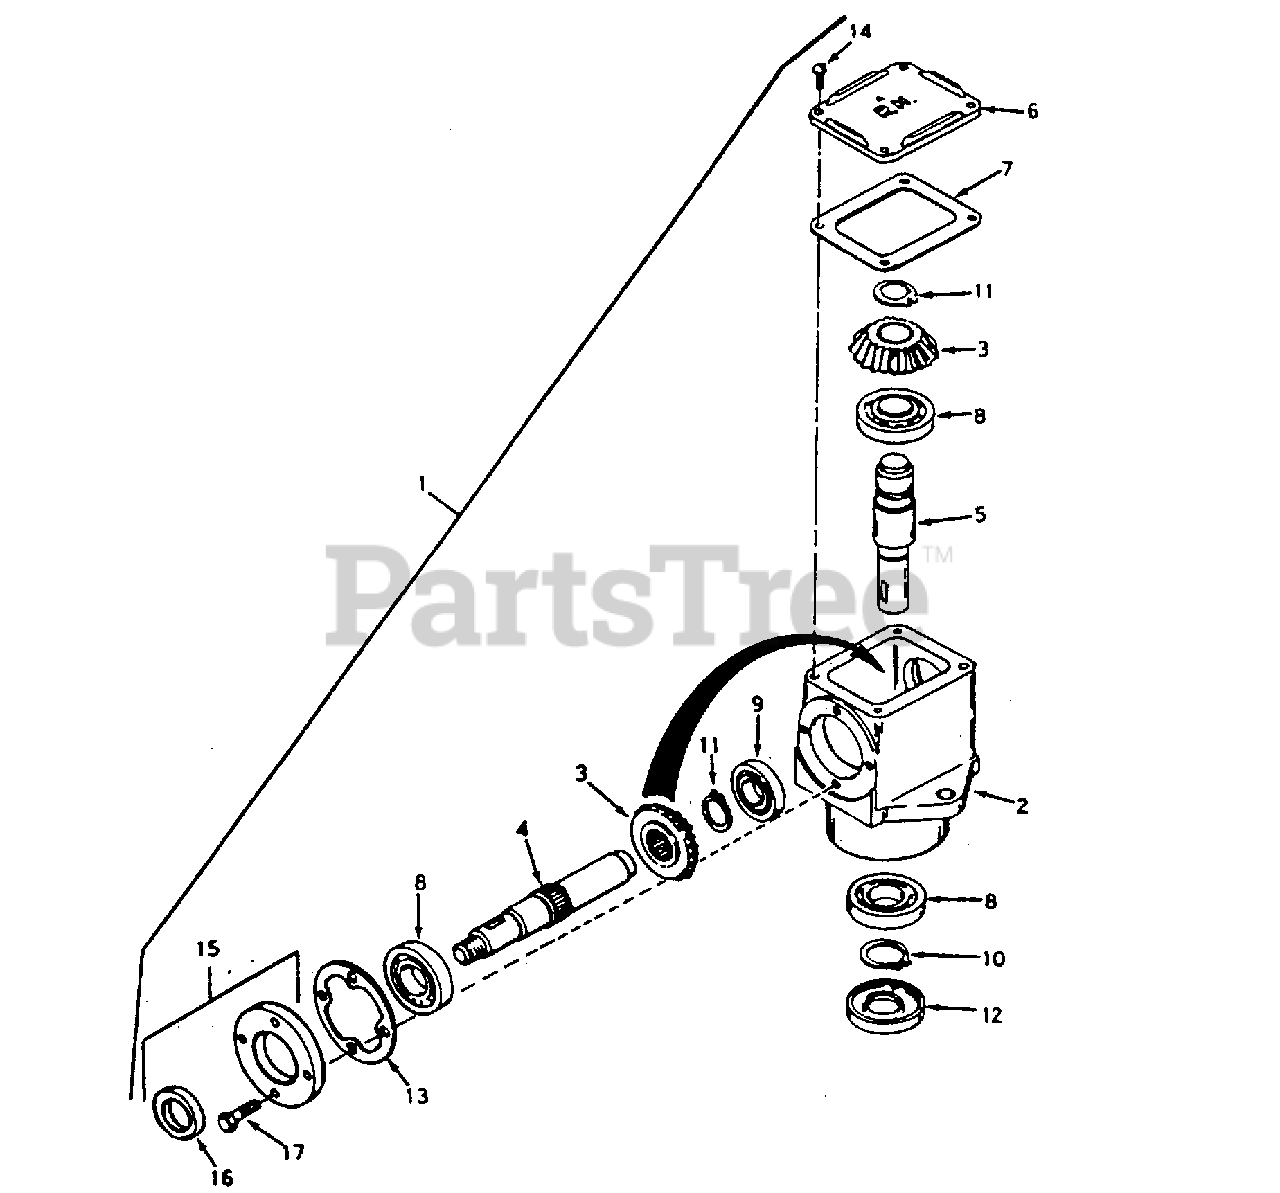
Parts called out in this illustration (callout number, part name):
1	Head Ass'y. R.H.
2	Housing, Right Angle Drive
3	Gear, Miter
4	Shaft, Input
5	Shaft, Output
6	Cover, Right Hand
7	Gasket, Cover
8	Bearing, Ball
9	Bearing, Ball
10	Ring, Snap
11	Ring, Snap
12	Seal, Oil
13	Gasket, Cap
14	Screw, Rd. Hd. Self-Tap. 10-24 x 1/2
15	Cap & Seal Ass'y., Retainer
16	Seal, Oil
17	Screw, Hex Hd. 1/4-20 x 7/8
